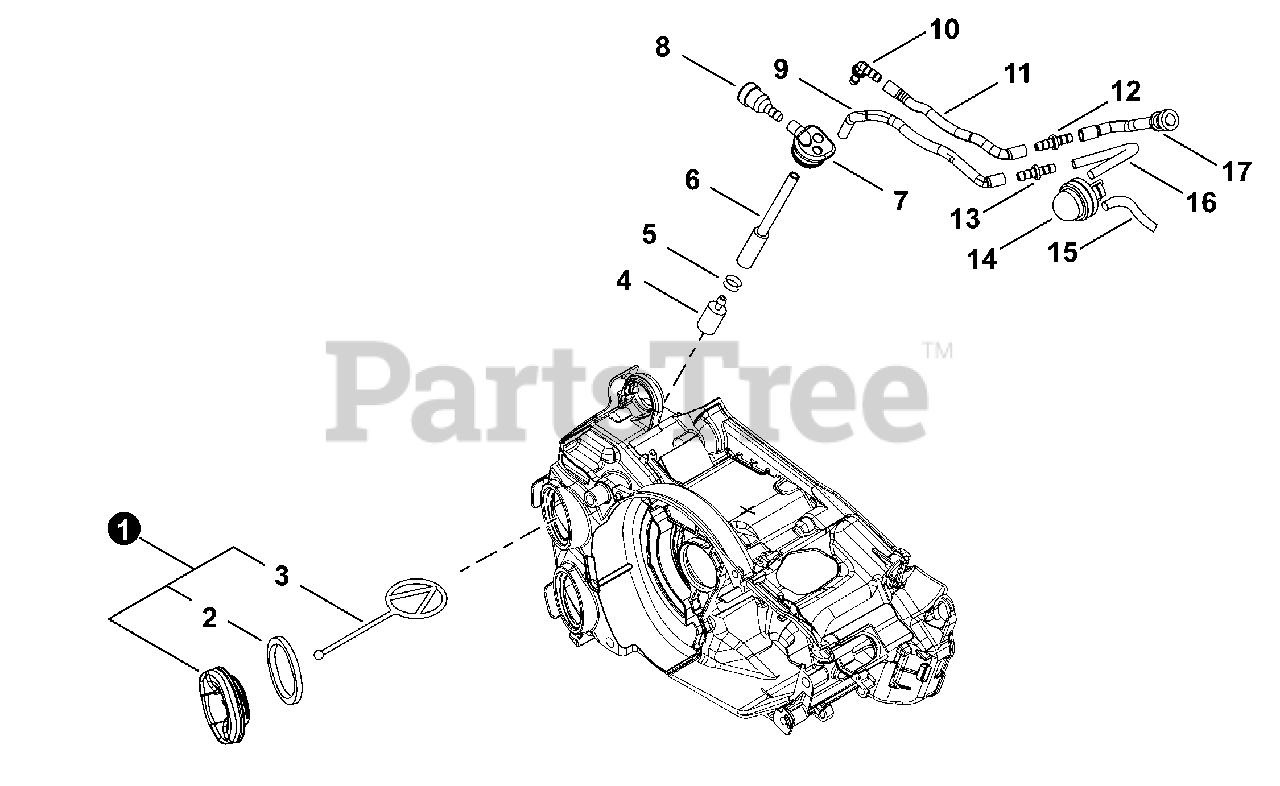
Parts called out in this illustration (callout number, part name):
1	CAP ASSY, FUEL
2	GASKET, CAP
3	CONNECTOR, CAP L= 60 MM
4	FILTER, FUEL
5	CLIP Ø6
6	PIPE, FUEL
7	GROMMET, FUEL
8	VENT ASSY
9	PIPE, FUEL 3×5×115
10	CONNECTOR, PIPE
11	PIPE, FUEL
12	CONNECTOR, PIPE
13	CONNECTOR, PIPE
14	BULB, PURGE
15	PIPE, FUEL
16	PIPE, FUEL 3×5×58L
17	PIPE, FUEL
